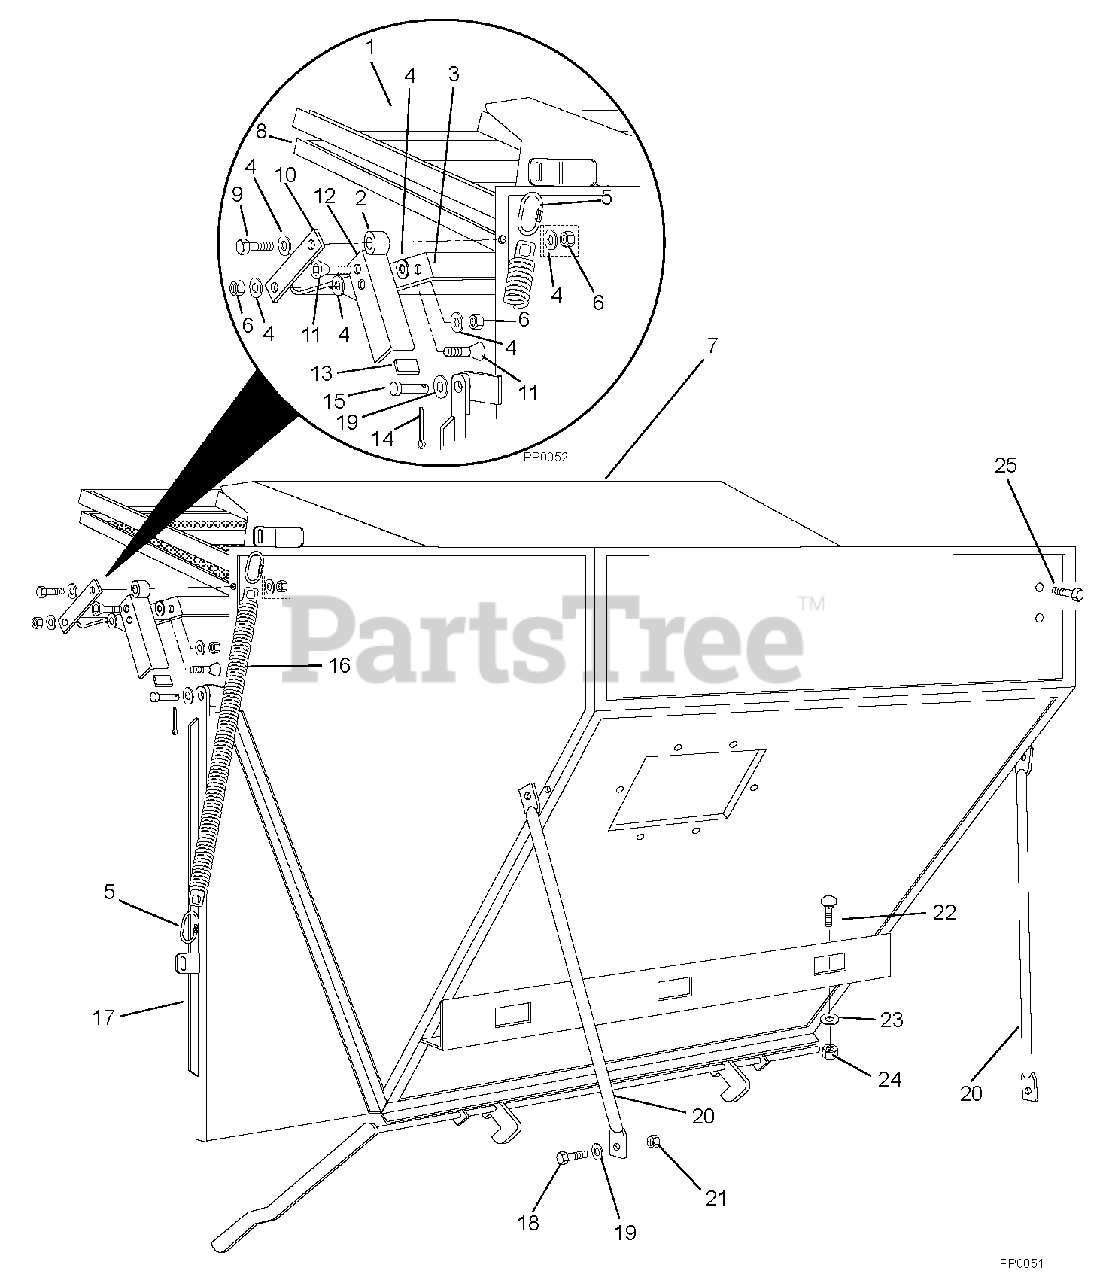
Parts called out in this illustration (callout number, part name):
1	Weldment, Grid
2	Link Spacer, Screen Door
3	Weldment, Screen Door
4	Washer, Flat .312
5	Quick Link .25
6	Hex Nut 5/16-18 CP Nylock
7	Weldment, Hopper
8	Screen, Single
9	Cap Screw, Hex Head .312-18 x 1.50
10	Linkage, Filter Door
11	Cap Screw, Flat Countersunk Head Hex Socket .312-18 x 1.00
12	Latch, Filter Door Right Hand
13	Gasket Material .75 x .25
14	Pin, Cotter .125 x .75
15	Pin, Clevis .38 x 1.125
17	Weldment, Door
18	Cap Screw, Hex Head .38-16 x 1.00
19	Washer, Flat .38
20	Brace, Hopper
21	3/8-16 Serrated Flange Nut
22	Bolt, Carriage .50-13 x 1.50
23	Washer, Flat .50
24	Nut, Lock .50-13
25	Cap Screw, Hex Head .38 x .75
